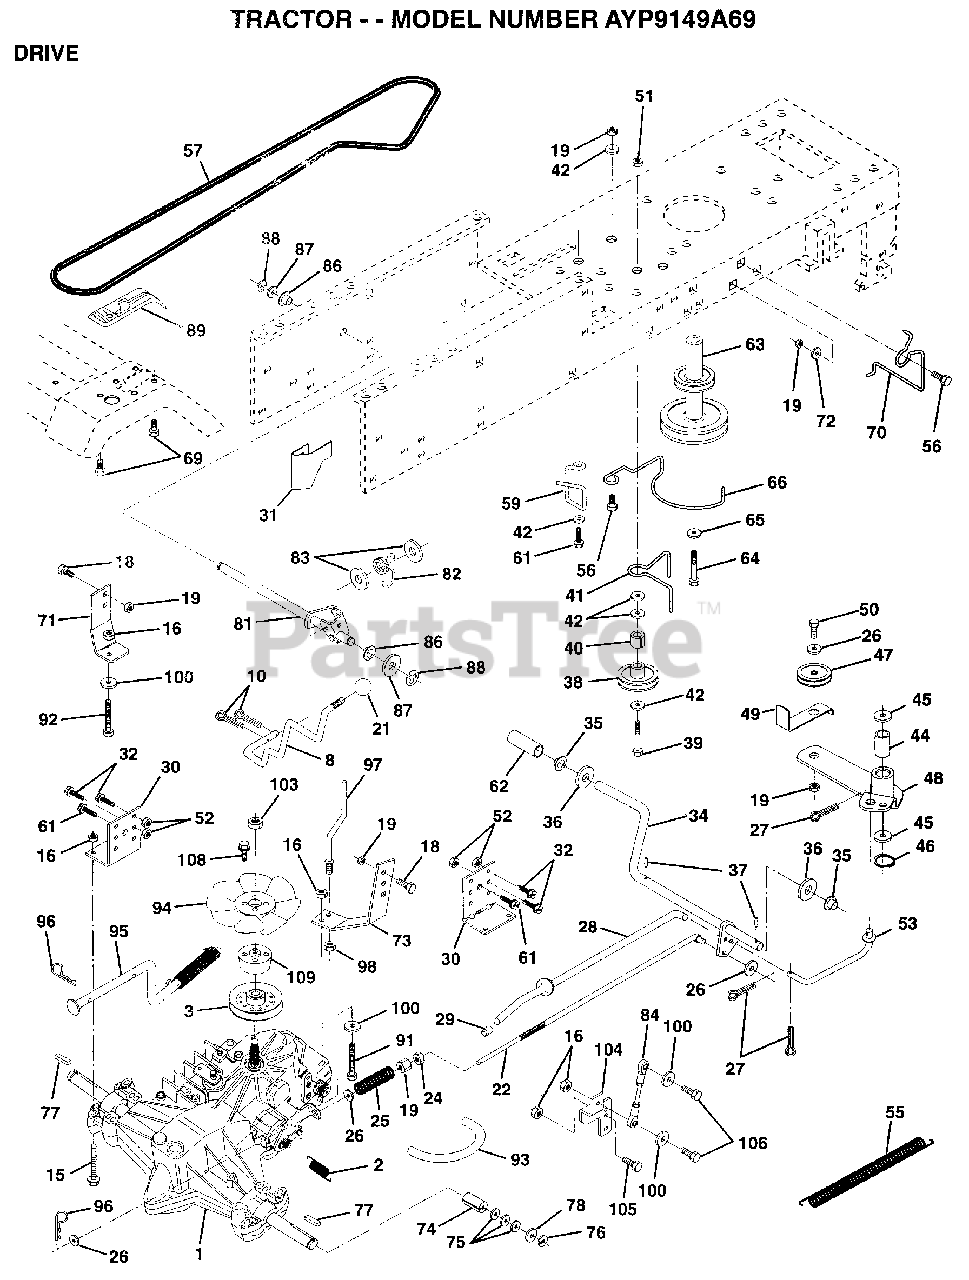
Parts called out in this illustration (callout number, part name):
1	TRANSAXLE HYD 0319-0500
2	SPRING RET BRAKE
3	PULLEY.4.20.HYDRO
8	ROD SHIFT FEND LT
10	PIN COTTER 1/8
15	BOLT.HX.FLG.5/16
16	NUT
18	BOLT
19	NUT
21	KNOB T (1/2-HOLE)
22	ROD.BRAKE.HYDRO.
24	NUT
25	SPRING ROD LT
26	WASHER
27	COTTER PIN
28	ROD.BRAKE.PARK.LT
29	PLUNGER CAP T
30	TRANSAXLE MTG BKT
31	"KEEPER,BELT LH T"
32	BOLT
34	SHAFT.PEDAL.FOOT
35	NYLON BEARING
36	WASHER LT
38	PULLEY.IDLER.FLAT
39	BOLT
40	SPACER T
41	BELT KEEPER LT
42	WASHER
44	"LY, BEARING"
45	WASHER LT
46	KLIP RING
48	ARM IDLER
49	RETAIN BELT
53	"LINK, CLUTCH T"
55	"SPRING, RETURN LT"
57	BELT-V.HYDR.84.61
59	KEEPER BELT CNTSP
61	SCREW
62	PEDAL COVER T
63	PULLEY.ENGINE
64	BOLT
65	LOCKWASHER
66	KEEPER.BELT.ENG.L
69	SCREW HEXWSH H-L
70	KEEPER BELT ENG
71	STRAP.TORQ.LH.HYD
72	WASHER
73	STRAP.TORQ.RH.HYD
74	SPACER SPLIT
75	WASHER
76	E-RING LT
77	SQUARE KEY
78	WASHER
81	SHAFT.CROSS.HYD
82	"SPRING,TORSION"
83	WASHER
83	"LINE FUEL HYD 4"""
84	ROD.TIE.BALL.HYD.
86	BUSHING
87	WASHER D
88	KLIP RING
92	HEX BOLT
94	"FAN 7"" HYDRO"
96	RETAINER M
97	KEEPER.BELT.RH.HY
98	NUT
100	WASHER M
104	ARM.CONTROL.PUMP
105	SCREW CAP 5/16-18
106	BOLT
108	SCREW.HXHD.10-20
109	ADAPTOR.FAN.HYDRO
